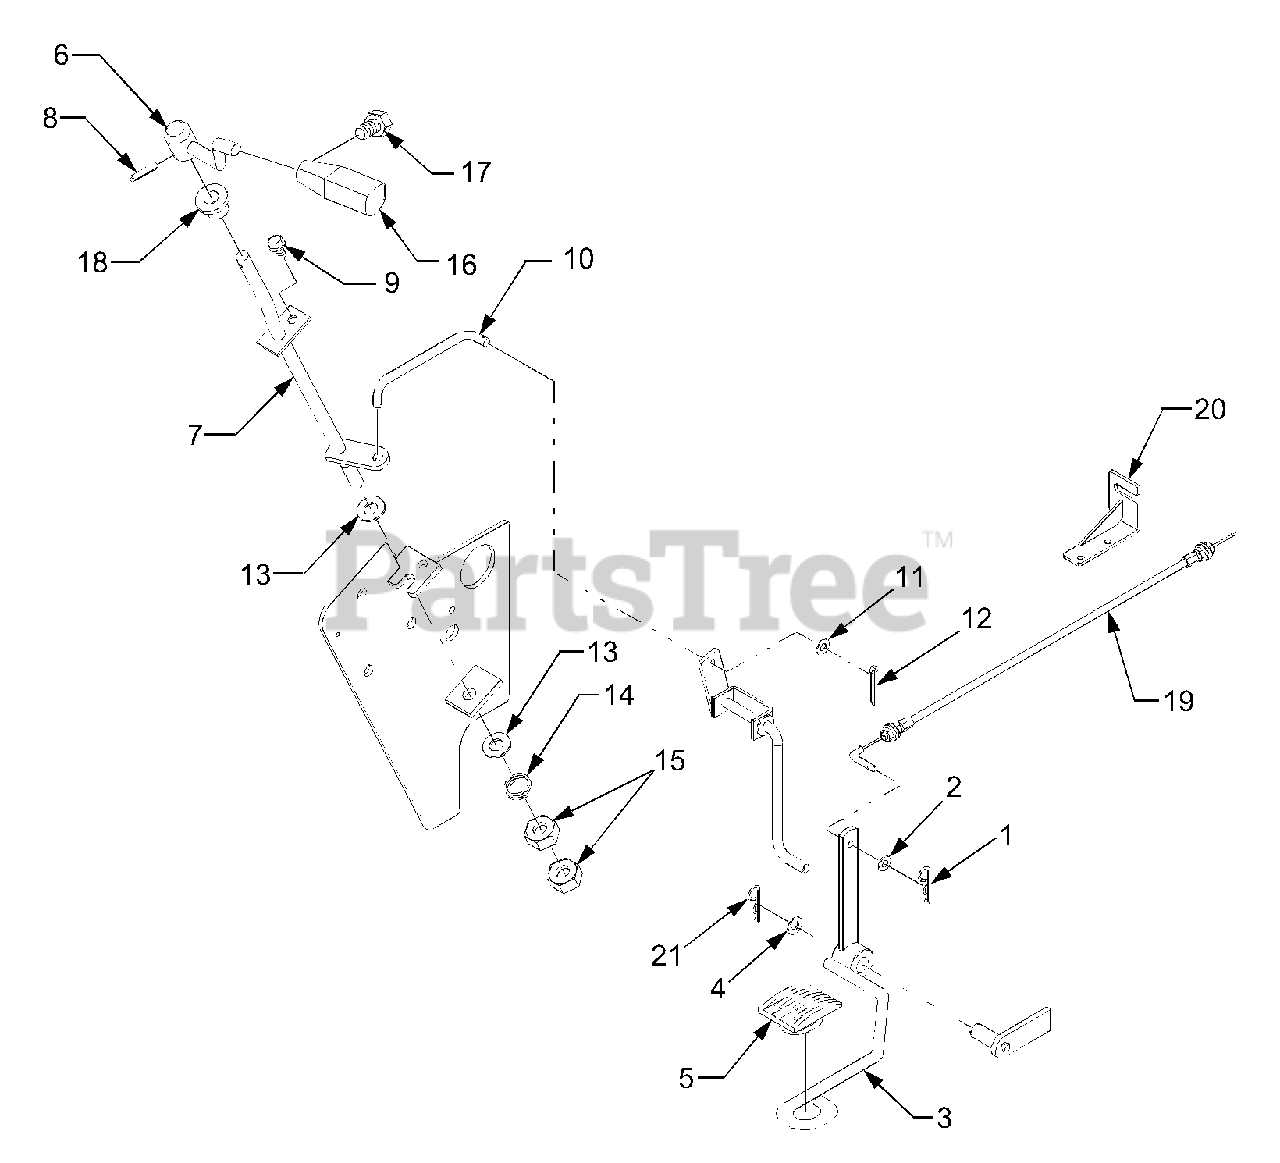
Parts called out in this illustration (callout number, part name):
2	Washer, Plain
3	Pedal, Accelerator
4	Washer, Plain
5	Rubber, Accel Pedal
6	Lever 1, Accel
7	Lever 2, Accel
9	Bolt, With Washer
11	Washer, Plain
13	Washer, Plain
16	Grip
19	Cable, Accelerator
